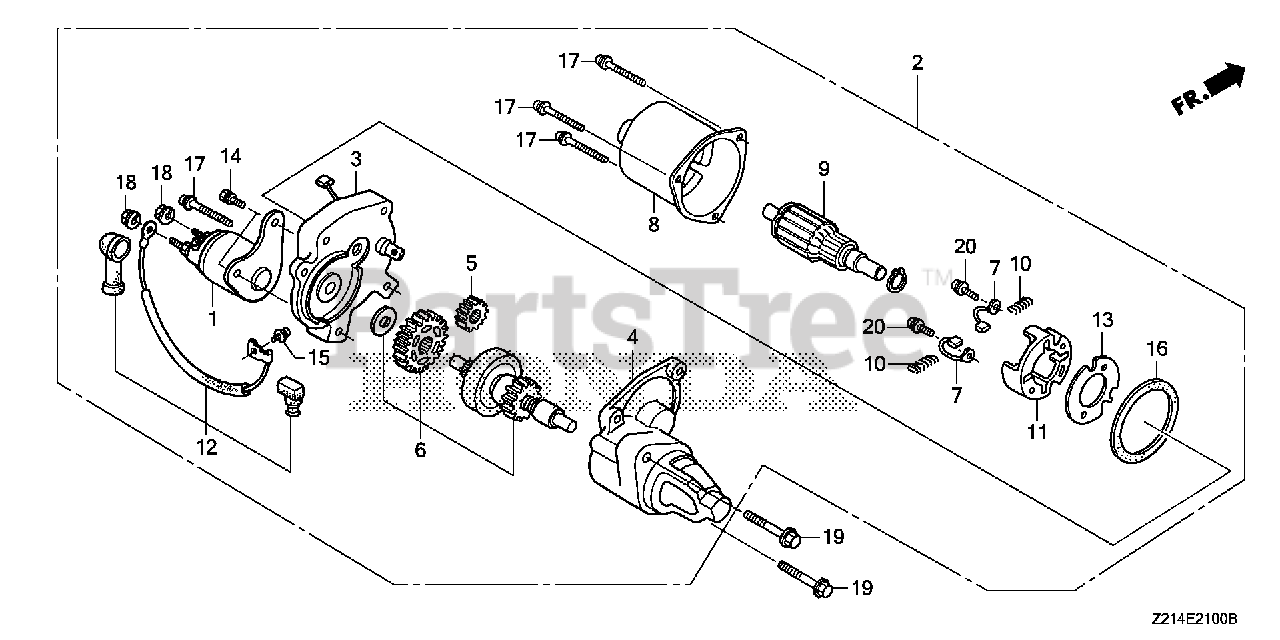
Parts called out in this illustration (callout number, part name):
1	CONTACTOR ASSY.
2	MOTOR UNIT, STARTER
3	BRACKET, CENTER
4	BRACKET, FR.
5	GEAR, DRIVE PINION
6	CLUTCH, OVERRUNNING
7	BRUSH
8	YOKE
9	ARMATURE
10	SPRING, BRUSH RETURN
11	HOLDER, BRUSH
12	WIRE, WATER COVER
13	INSULATOR
14	BOLT-WASHER (5X14)
15	SCREW-WASHER (4X6)
16	GASKET
17	SCREW-WASHER (5X3)
18	NUT-WASHER (6MM)
19	BOLT, FLANGE (8X40) Use up to Engine SN 1003236.
20	SCREW-WASHER (4X14)
